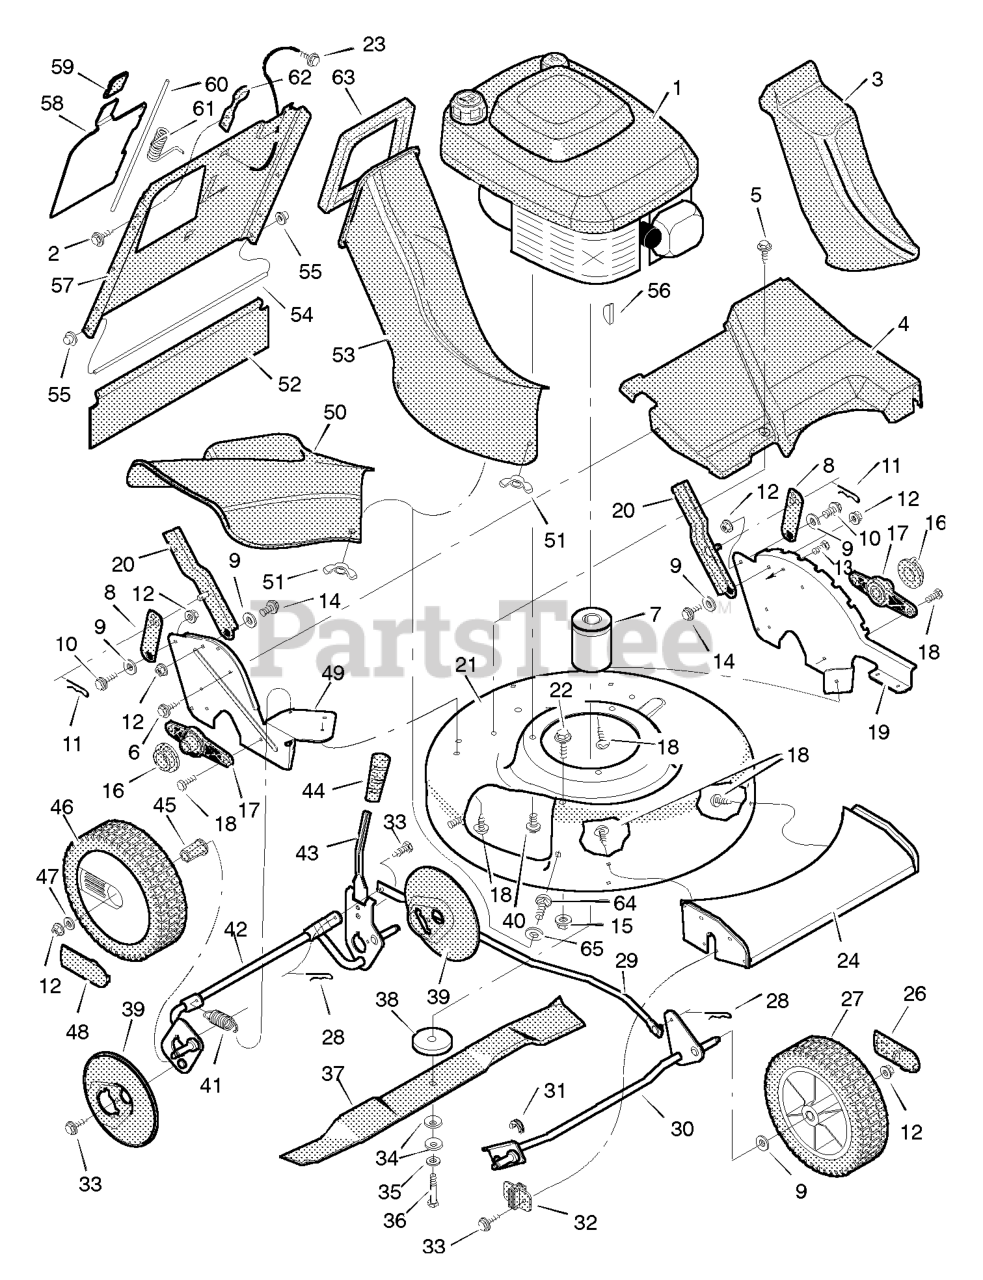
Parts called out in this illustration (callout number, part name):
1	Engine *
2	Screw
3	Plug, Mulcher
4	Cover, Rear
7	Adapter, Blade
8	Strap, Adjuster
9	Washer, Spring
10	Bolt, Shoulder
11	Pin, Hair
12	Locknut, Flange
14	Bolt, Shoulder
15	Locknut, Flange
16	Bearing, Lifter
17	Support, Axle
19	Index (Red)
20	Bracket, Handle
21	Housing (Red)
22	Bolt, Shoulder
24	Panel, Front (Red)
26	Cap- Ball Bearing (Gray)
27	WHEEL & TIRE ASSEMBLY, White, 8"
28	Pin, Hair
29	Link, Lifter
30	Crossbar Assembly, Front
31	Bushing
32	Clip, Front Axle
34	Washer, Belleville
36	Bolt, Hex
38	Spacer, Adapter
39	Cover, Dust
40	Bolt, Engine
41	Spring, Extension
42	Crossbar Assembly, Rear
43	Lever, Height Adjuster
44	Grip, Height Adjuster
45	Bushing
46	Wheel, Rear (White)
47	Washer
48	Hub Cap (Gray)
49	Support, Wheel (Red)
50	Deflector, Chute
51	Nut, Wing
52	Guard, Rear
53	Deflector, Rear
55	Cap, Push On
56	Key, Woodruff #6
57	Plate, Bagger
58	Door, Rear
59	Grip, Door
60	Rod, Door
61	Spring, Torsion
62	Guide, Rope
64	Bolt, Carriage
65	Retainer
